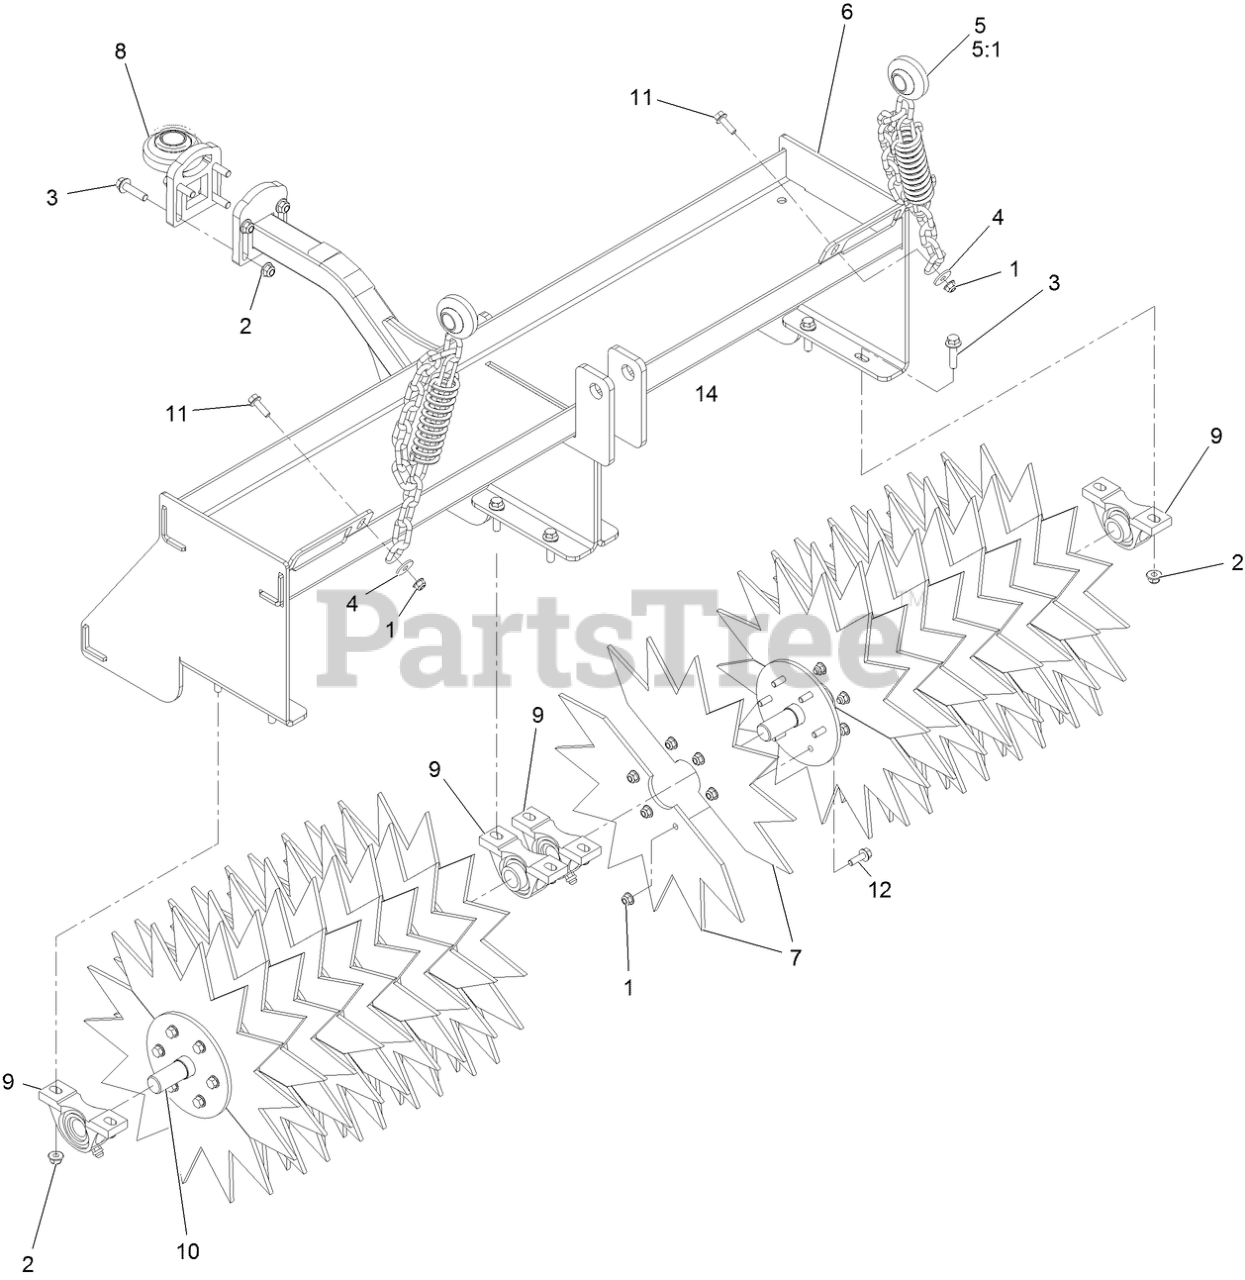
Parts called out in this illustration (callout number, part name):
1	NUT-HF, NI
2	NUT-HF, NI
3	SCREW-HHF
4	WASHER-FLAT
5	SWIVEL-CHAIN ASM
5:1	Z-PLUG DRAWBAR SPRING
6	HEAD-AERATION, 40""
7	STAR, SPIKER HEAD
8	MOUNT-SWIVEL BRG,AER HEAD
9	PILLOW BLOCK BEARING
10	DISC-SPYKER HEAD
11	SCREW-HH
12	SCREW-HHF
14	DECAL-WARNING
